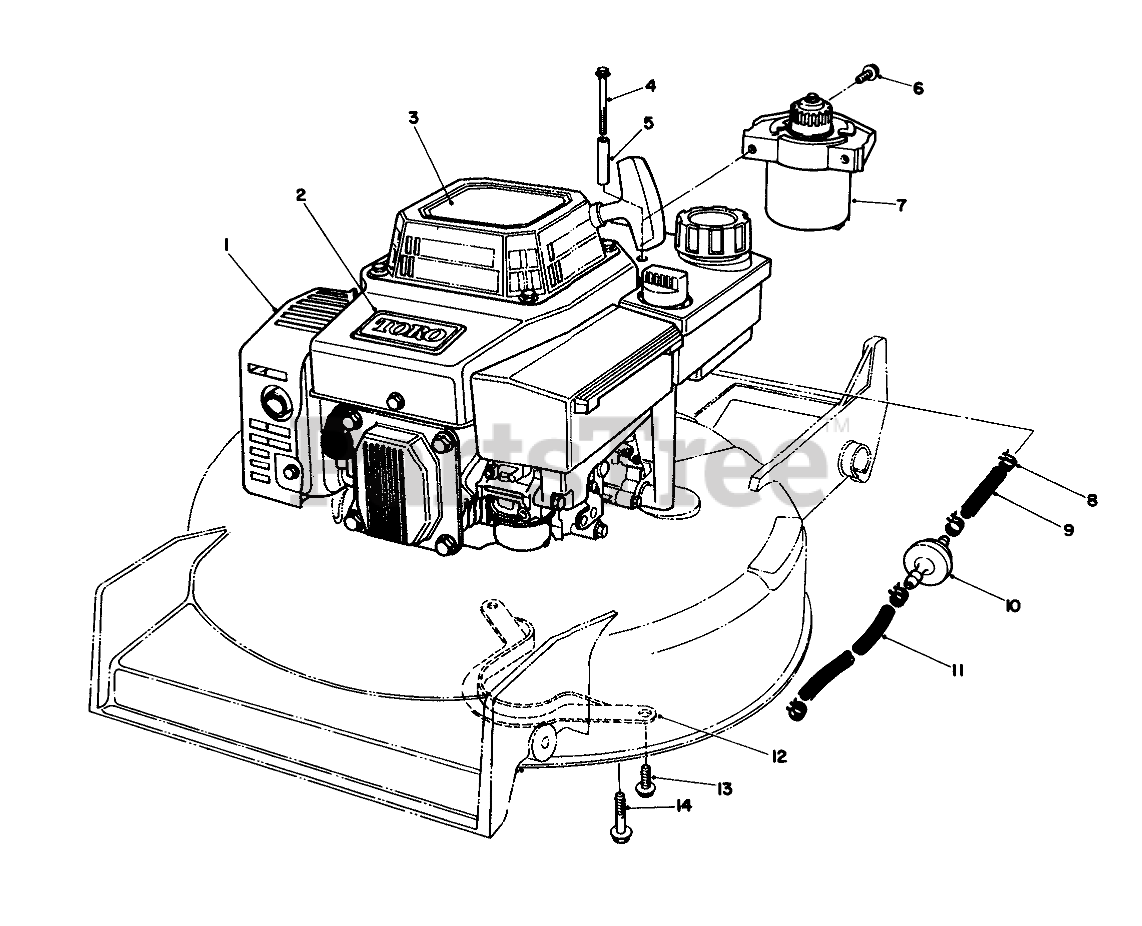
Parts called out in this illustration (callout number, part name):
1	Engine-OHV
2	TORO LOGO PLT
3	DECAL-HV INT'L
4	THRD FORMING SCREW
5	TUBULAR SPACER
6	SCREW
7	Starter Motor Assembly
8	CLAMP-FUEL LINE
9	LINE-GAS
10	FILTER-FUEL
11	HOSE-FUEL
12	BBC BELT GUIDE
13	Screw
14	SCREW-HWHTF
